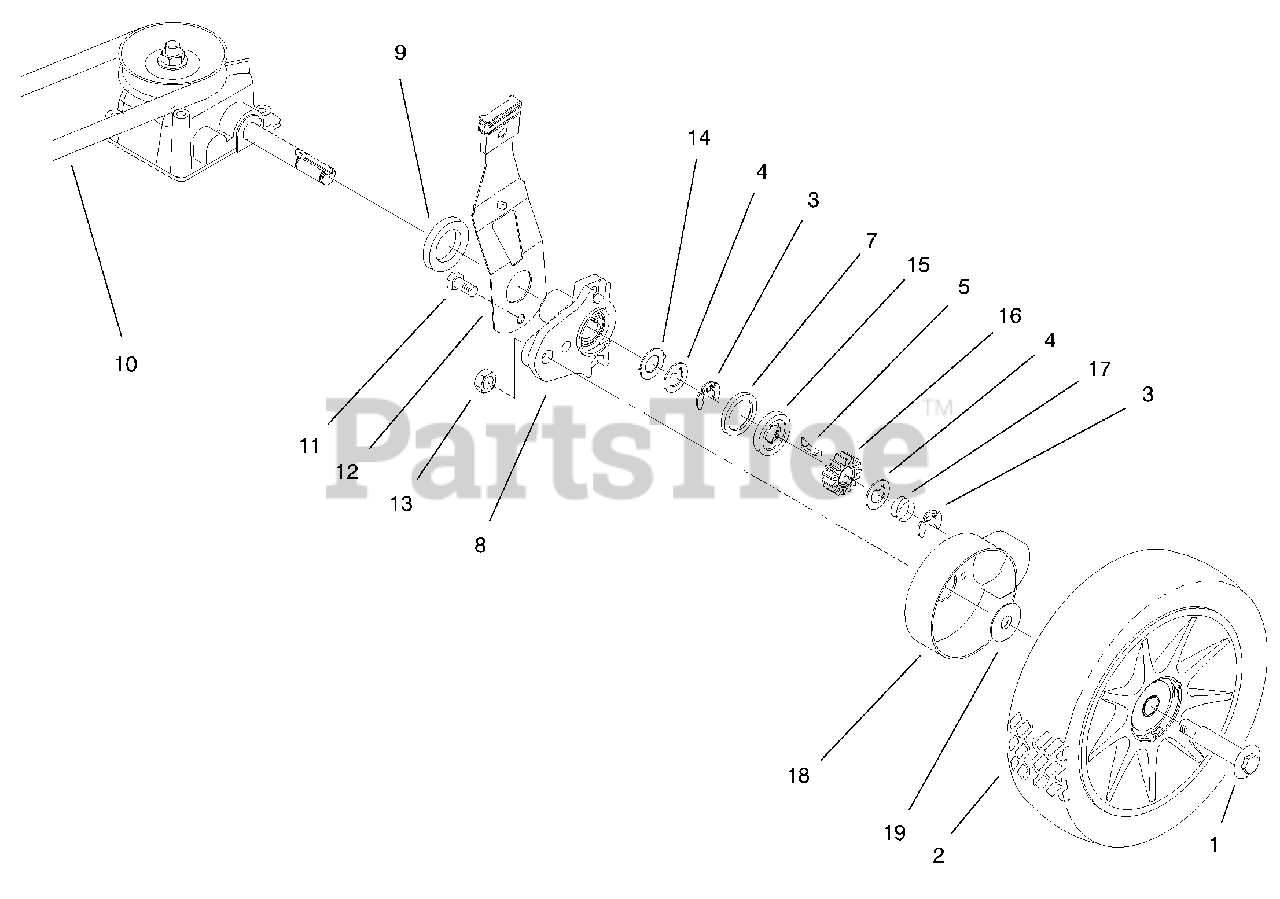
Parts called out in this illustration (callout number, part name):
1	Bolt-Shoulder
2	Wheel & Tire Assembly 8"
3	Ring-Retaining
4	Washer-Thrust Keyed
5	Key-Rocking L.H.
7	Ring-Friction
8	Arm-Height Adj. Rear
9	Spacer-Axle Shaft
11	Screw-Hex Hd.
12	Spring Arm Assembly
13	Nut-Lock
14	Washer-Thrust
16	Gear-Pinion
17	Spring-Compression
18	Cover-Wheel
19	Washer-Stepped
